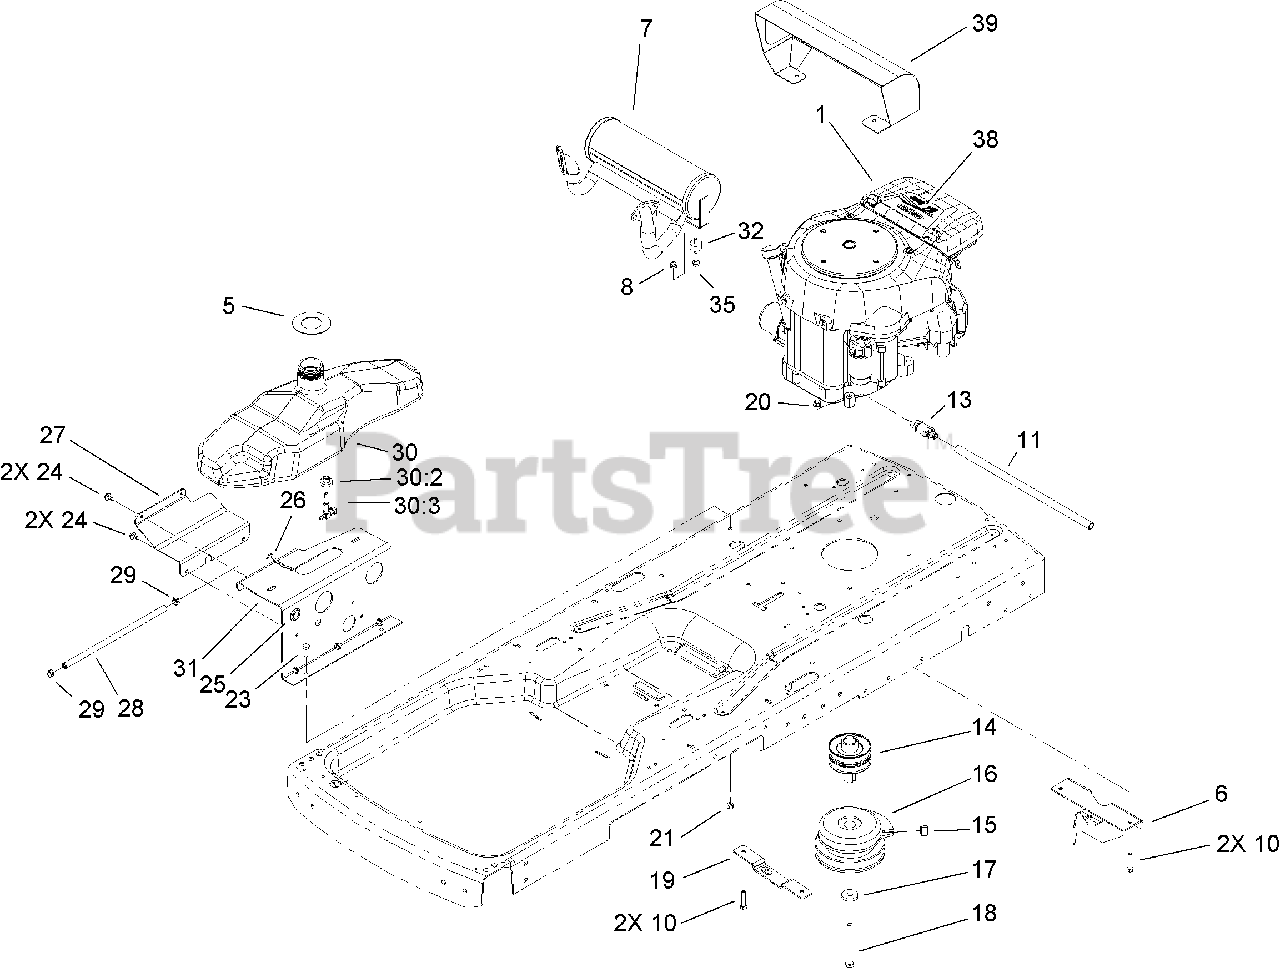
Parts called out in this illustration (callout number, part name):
5	SEAL-FOAM
6	BRACKET-PIVOT
10	SCREW-HH
11	TUBE-DRAIN, OIL
13	VALVE-DRAIN, OIL
14	PULLEY-ENGINE
16	CLUTCH-ELECTRIC
18	SCREW-HH
19	PLATE-MOUNT, IDLER
21	NUT-LOCK, NI
23	SCREW-HH
24	SCREW-HHF
27	PLATE-SUPPORT
28	HOSE-FUEL
30	FUEL TANK ASM
30:3	VALVE-FUEL
32	ISOLATOR-RUBBER
38	DECAL-ENGINE
39	SHIELD-MUFFLER
